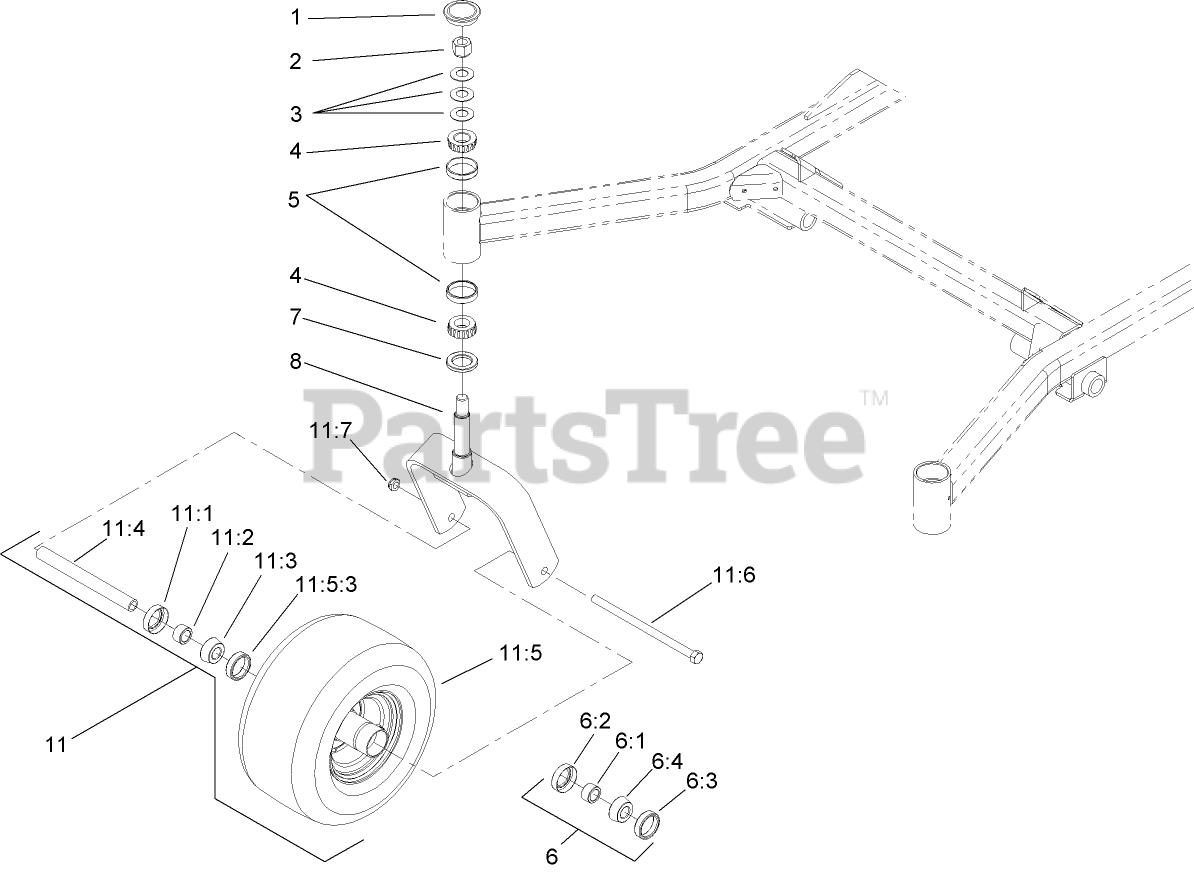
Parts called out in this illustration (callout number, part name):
1	CAP-GREASE
2	NUT-LOCK, NI
3	WASHER-BELLVILLE
4	BEARING-CONE, TAPERED
5	BEARING-CUP, TAPERED
6	CASTER WHEEL BEARING KIT
6:1	SPACER-BEARING
6:2	SEAL-BEARING
6:3	BEARING-CUP
6:4	BEARING-CONE, TAPER
7	SEAL-GREASE
8	CASTER-FORK
11	CASTOR WHEEL ASM
11:1	SEAL-BEARING
11:2	SPACER-BEARING
11:3	BEARING-CONE, TAPER
11:4	SPACER-CASTER, FRONT
11:5	WHEEL AND TIRE ASM (SEMI-PNEUMATIC)
11:5:3	BEARING-CUP
11:6	SCREW-HH
11:7	NUT-LOCK, NI
